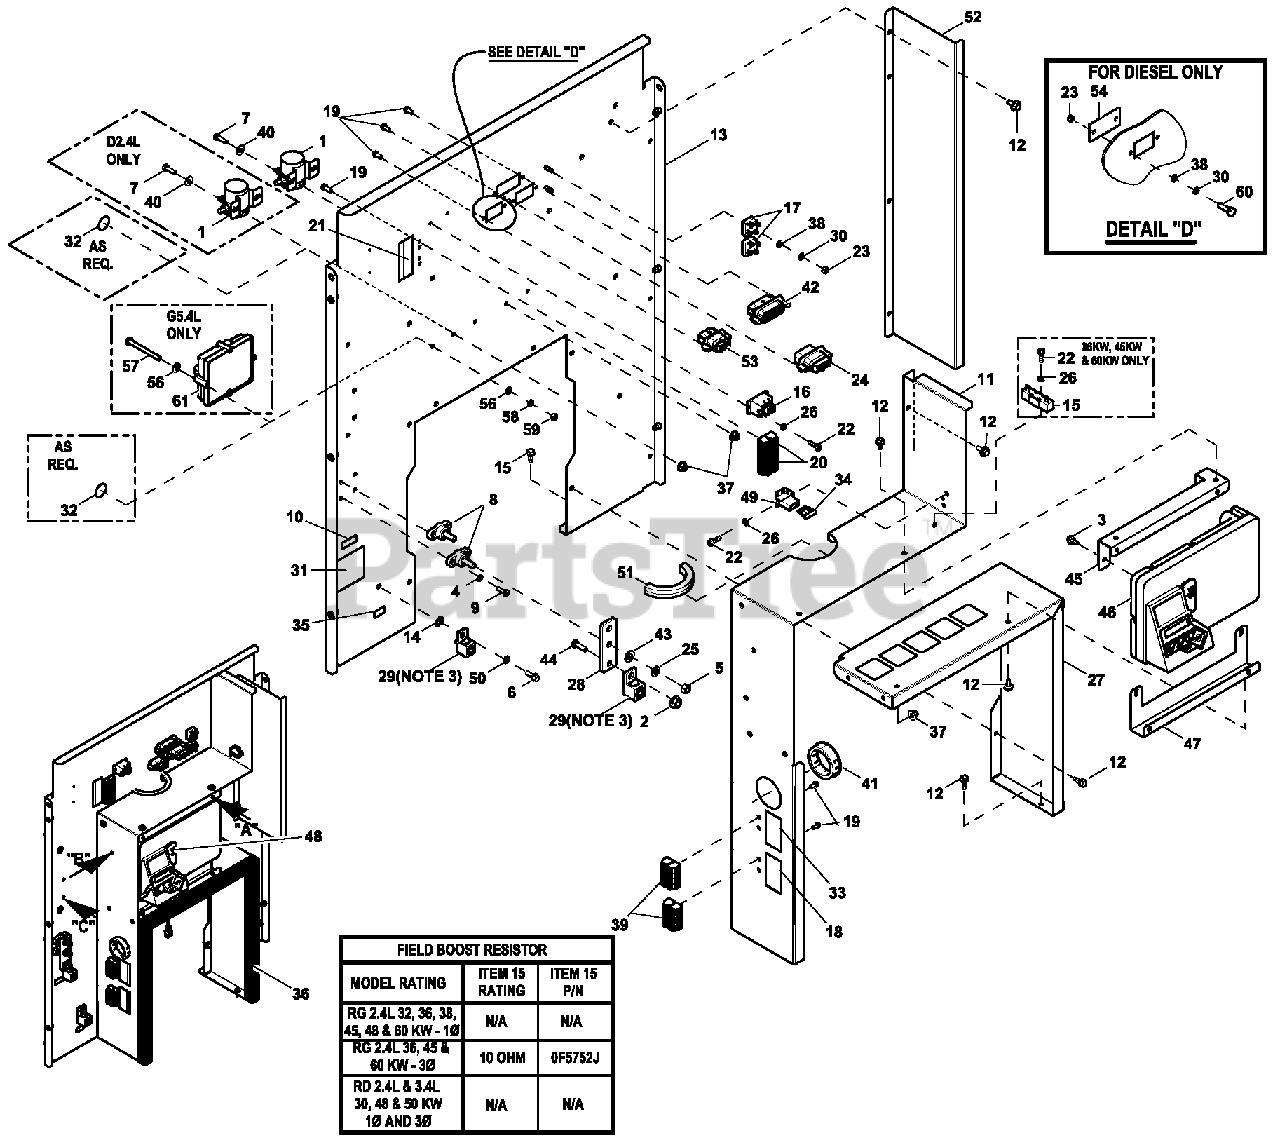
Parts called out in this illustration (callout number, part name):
1	RELAY SOLENOID 12VDC PNL MNT
2	NUTHEXFLWHIZM8-1.25
3	SCREW HHTT M6-1.0X 1 2 ZINC
4	WASHER LOCK #8-M4
5	NUT HEX 3/8-16 STEEL
6	SCREW HHTT M6-1.0X 2 5 ZINC
7	SCREW HHC M6-1.0X20 C8.8
8	JUNCTION BLOCK 3/8-16
9	SCREW PHTT M4-0.7 X 12 ZP
10	DECAL, NEUTRAL
11	CONNECTION BOX LH SIDE C2 CPL
12	SCREW HWHTF M6-1.0 X 16
13	CONNECTION BOX CENTER C2 CPL
14	WASHER LOCK SPECIAL 1/4"
15	RES WW 10R 5% 25W QK CONN (SEE TABLE)
16	RELAY 12V 30A SPST PILOT DUTY
17	DIODE BRIDGE 1P35A 1000V
18	DECAL TB2&TB3 CUST CONNECTIONS
19	SCREW HHSP #10 X 3/8 HI-LOW
20	TERM BLOCK 3PUL12-20AWG
21	DECAL CONBOX TB1 CONNECTIONS
22	SCREW PHTT #6-32 X 1/2 ZYC
23	NUT HEX M5-0.8 G8 CLEAR ZINC
24	MX150L SLRRMNT 22-18 12P W/OGA
25	WASHER LOCK 3/8
26	WASHER LOCK #6
27	CONNECTION BOX RH SIDE C2 CPL
28	BUS BAR NTRL BLK 15-250A
29	LUG SLDLSS 300 MCM-6 AL/CU
30	WASHER LOCK M5
31	DECAL CAUTION ELEC SHOCK SM
32	SEAL WEATHER .63"DIA
33	DECAL CUST POWER CONNECTION
34	FUSEATO TYPE 15 AMP (BLUE)
35	DECAL GROUND LUG
36	TAPE FOAM 1X1 (54"LG)
37	NUT FLANGE M6-1.0 NYLOK
38	WASHER FLAT M5
39	TERM BLOCK 4PUL12-20AWG
40	WASHER FLAT 1/4-M6 ZINC
41	BUSHING SNAP SB-2.5-31
42	MX150L RRMNT PLG 16P W/O G A
43	WASHER FLAT 3/8-M10ZINC
44	SCREW HHC M8-1.25X25 C8.8
45	CONTROLLER TOP STANDOFF
46	ASSY CONTROLLER PROTECTOR CPL
47	CONTROLLER BOTTOM STANDOFF
49	HOLDER FUSE WICKMANN ATO STYLE
50	WASHER LOCK M6-1/4
51	TRIM VINYL BLACK 1/8GP (6"LG)
52	DEFLECTOR AIR INTAKE C2
53	MX150L SLRRMNT 22-18 10P W/OGA
54	10 PIN CONN BLOCK OFF PLATE
56	WASHER FLAT #10 ZINC
57	SCREW PPHM #10-32X2
58	WASHER LOCK #10
59	NUT HEX #10-32 STEEL
60	SCREW HHC M5-0.8 X 16 G8.8
61	ASSY PROG 2010 IGN MOD 8 CYL
